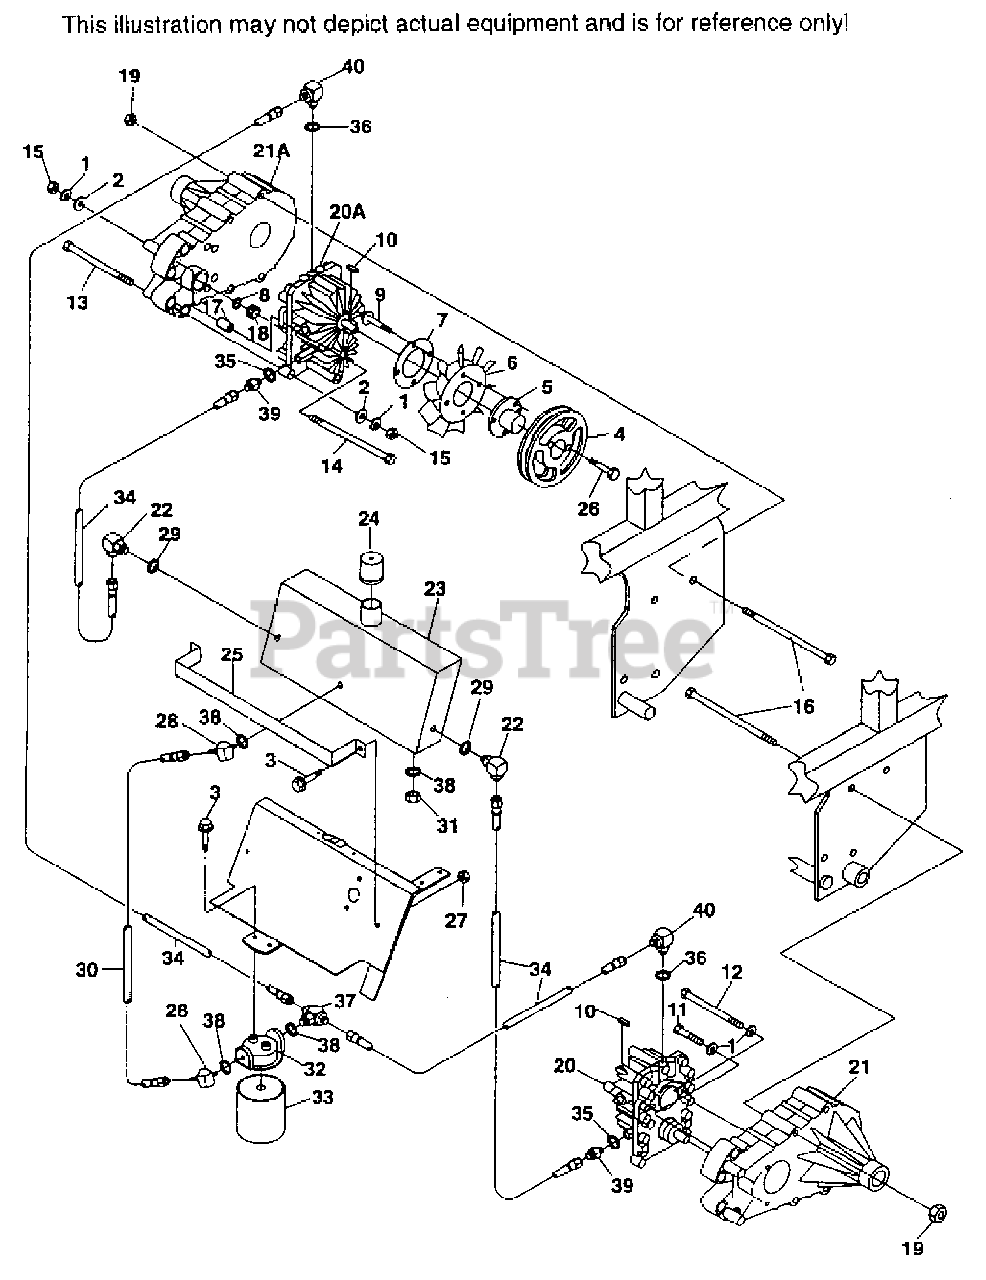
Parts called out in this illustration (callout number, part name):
3	CAP SCREW, 1/4-20 X 3/4" SERRATED FLANGE HEX
4	PUMP PULLEY
5	TAPERED HUB, 15MM BORE
6	FAN
7	BACK-UP WASHER
8	SNAP RING
9	CAP SCREW, 1/4-20 X 1/2" SERRATED FLANGE HEX
10	KEY, 5 X 5 X 25MM
12	HEX HEAD BOLT 5/16-18 X 4-1/2"
13	HEX HEAD BOLT 5/16-18 X 5"
14	HEX HEAD BOLT 5/16-18 X 7-1/2"
17	SPACER
18	GEAR
19	NUT, 3/8-16 SERRATED FLANGE HEX HEAD
20	PUMP, LH(INCLUDES SPACERS)
20A	PUMP, RH(INCLUDES SPACERS)
21	AXLE, LH,(INCLUDES BRAKE LEVER)
21A	AXLE, RH,(INCLUDES BRAKE LEVER)
22	90 DEGREE ELBOW, 9/16-18 JIC TO 9/16-18
23	OIL TANK RESERVOIR
24	CAP, OIL RESERVOIR
25	OIL RESERVOIR STRAP
27	NUT, 1/4-20 ELASTIC STOP
28	45 DEGREE ELBOW, 3/4-16 JIC TO 3/4-16
29	"O" RING, 5/64 X 15/32 ID
30	HOSE ASSEMBLY, FILTER INLET
31	PLUG, 3/4-16 "O" RING
32	HEAD, OIL FILTER
33	OIL FILTER, SPECIAL
34	HOSE ASSEMBLY
35	"O" RING, 3/32 X 3/4 ID
36	"O" RING, 1/16 X 3/8 ID
37	1/2", T-FITTING, 3/4-16 JIC TO 3/4-16
38	"O" RING, 3/32 X 5/8 ID
39	TUBE UNION, 3/4-16 JIC TO 7/8-14 "O" RING
40	90 DEGREE ELBOW, 9/16-18 JIC TO 7/16-20
